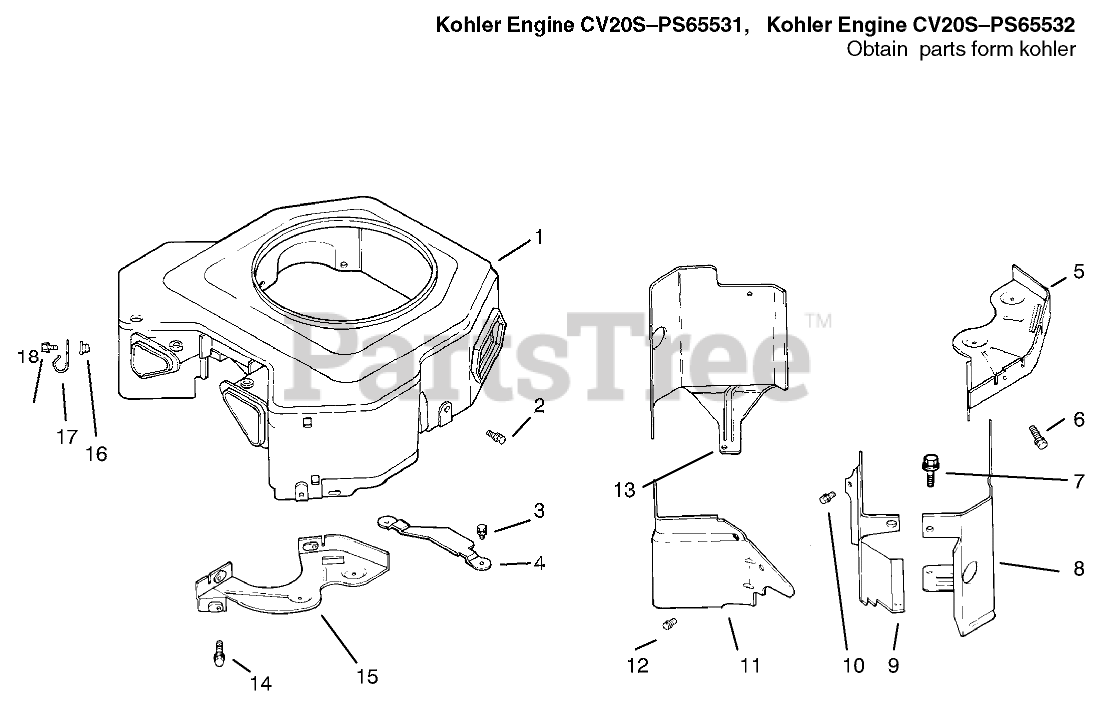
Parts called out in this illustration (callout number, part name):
1	Blower Housing ASM
3	Screw
4	Guard-Flywheel
5	Plate-Backing #2 Side
7	Screw
8	Baffle-Cylinder, #2
9	Baffle-Valley #1 Side
10	Screw
11	Baffle-Valley #2 Side
13	Baffle-Cylinder #1Side
14	Screw
15	Plate-Instruction
16	Nut
17	Clamp
18	Screw
